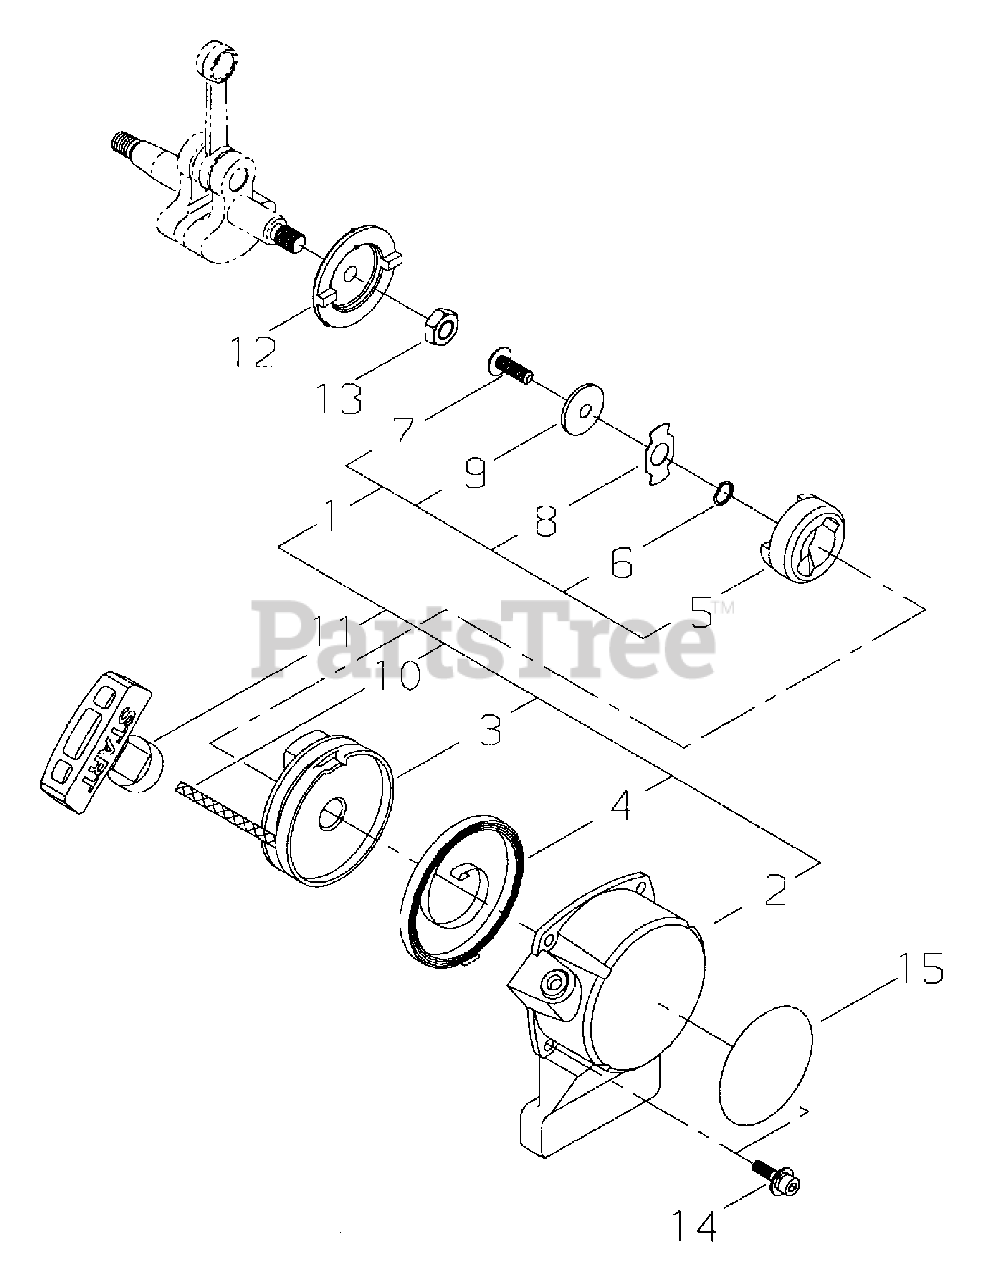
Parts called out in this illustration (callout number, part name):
1	STARTER ASSY
2	CASE, STARTER
3	REEL, ROPE
4	SPRING, REWIND
5	PAWL, STARTER
6	WASHER - SPRING
7	SCREW - 5
8	RETAINER
9	WASHER - 5
10	ROPE, STARTER
11	GRIP, STARTER
12	PAWL
13	NUT - 8
14	SCREW - 4X16
15	LABEL - C4
